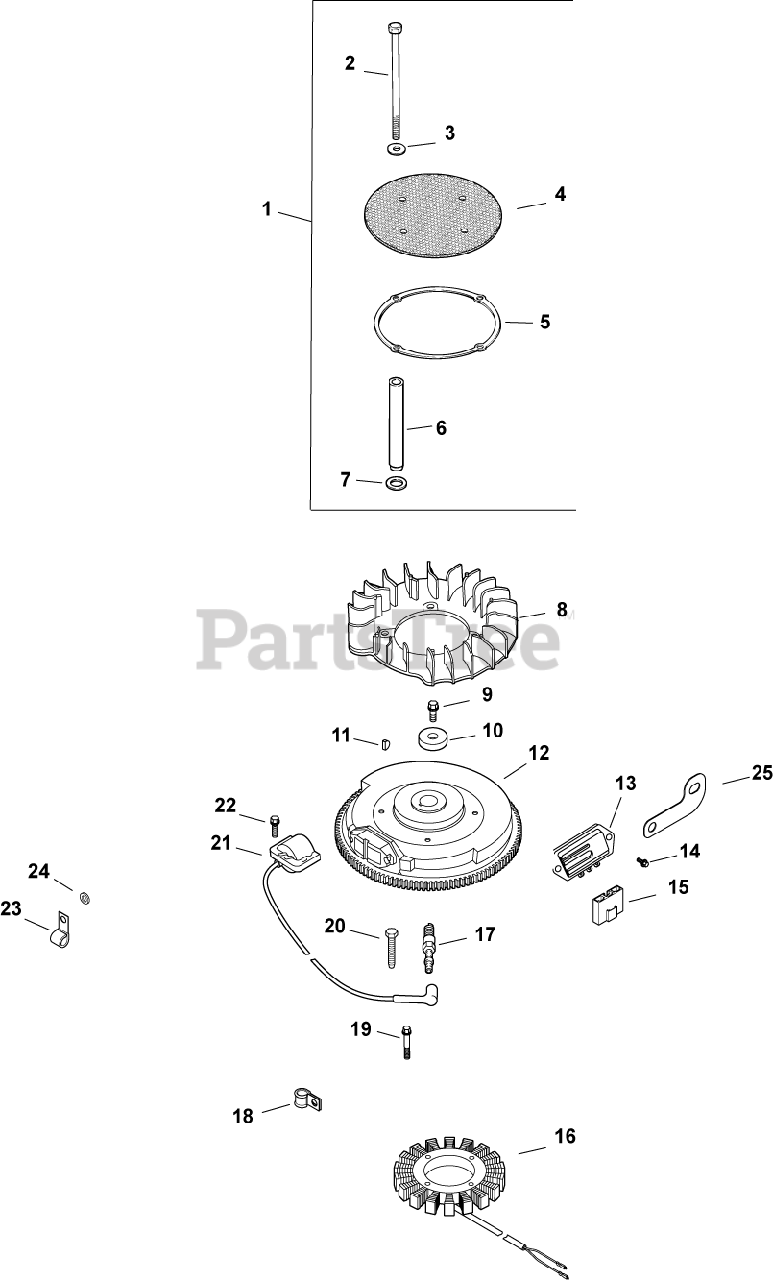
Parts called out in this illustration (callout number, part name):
1	KIT, CHOPPER SCREEN
2	SCREW, CAP M6X1.0X99.5
3	WASHER, FLAT 1/4" (O.D. 5/8")
4	SCREEN, GRASS
5	RING, SUPPORT USE 25 141 08-S
7	WASHER, SPRING 10 MM
8	FAN (DOMED)-USE 24 157 17-S
9	SCREW, FLG M10X1.5X45 - (#25086361S)
10	WASHER, FLAT 13/32"
11	KEY, 3/16" X 5/8"
12	FLYWHEEL ASSEMBLY
13	REGULATOR/RECTIFIER
14	SCREW, HEX FLANGE HI-LO
15	CONNECTOR
16	KIT, 15 / 20 AMP STATOR
17	SPARK PLUG, RFI
19	SCREW, SKT SET #10-24X1/4"
20	SCREW, M5X0.8X25 - (#25086402S)
21	KIT, MODULE IGNTN (CDI FIXED)
22	SCREW, FLG THD FRM M5X.8X20-(#25086399S)
23	CLIP, CABLE
24	WASHER, FLAT 1/4" (O.D. 1/2")
25	BRACKET, GROUND STRAP USE 24 518 12-S
